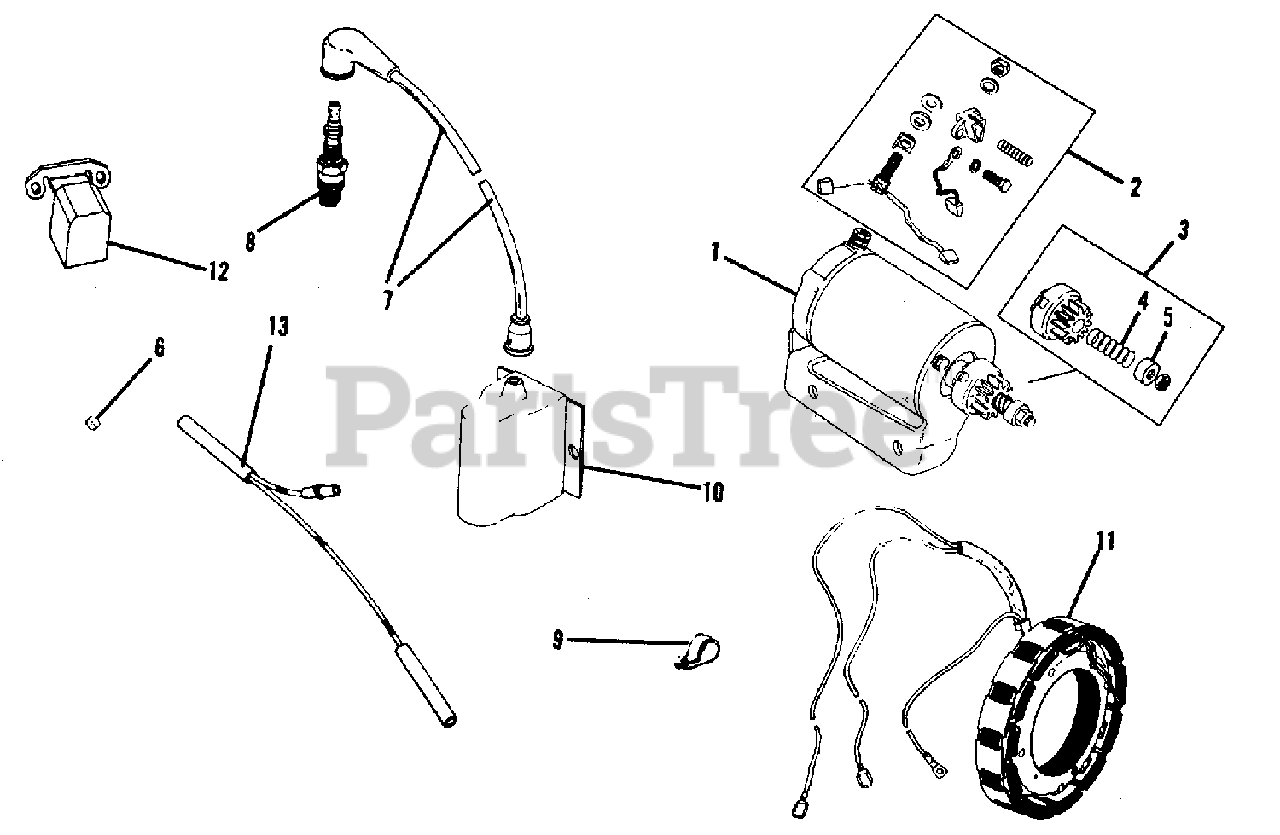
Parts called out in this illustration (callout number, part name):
1	STARTER ASSEMBLY, Engine (Includes Items 2 thru 5)
2	KIT, Brush & Spring
3	KIT, Starter Drie (Includes Items 4 & 5)
4	SPRING, Anti-Drift
5	SPACER, Gear Stop
6	PLUG, Cup
7	CABLE, Hight Tension
8	PLUG, Spark
10	COIL ASSEMBLY, Ignition
11	STATOR ASSEMBLY, Generator
12	TRIGGER ASSEMBLY, Ignition
13	LEAD, Stop
